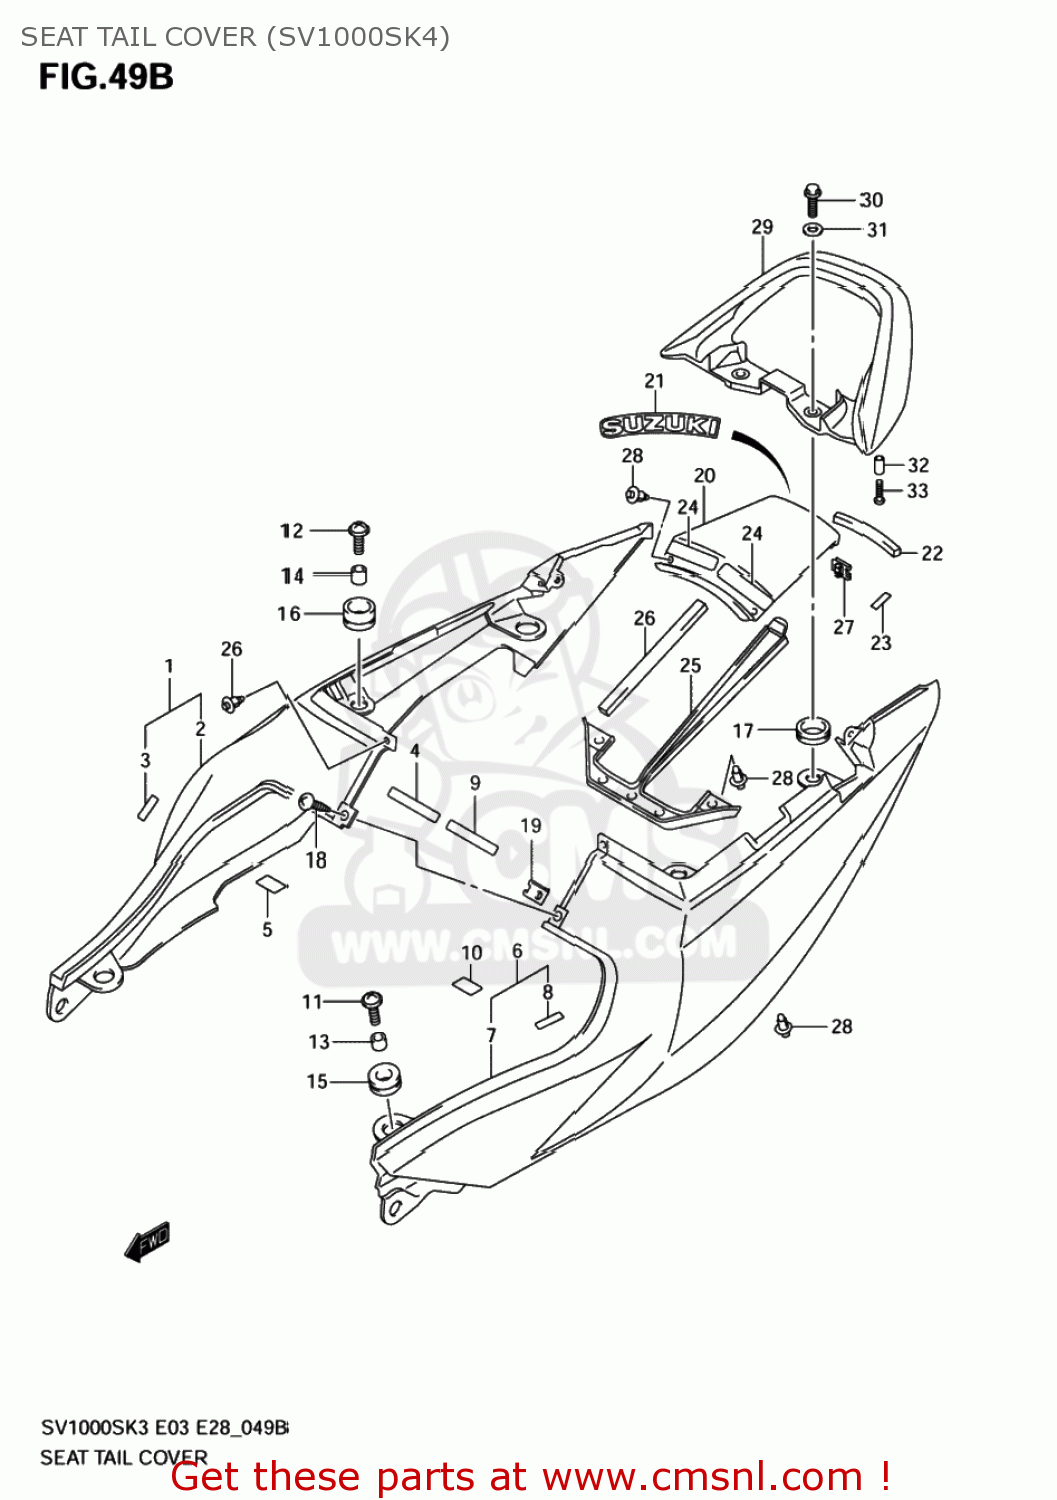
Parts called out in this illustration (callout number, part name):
1	COVER,SEAT TAIL
2	COVER,SEAT TAIL
3	TAPE,COVER
4	TAPE,SEAT TAIL COVER NO.2 FR
5	PROTECTOR,FRAME COVER
6	COVER,SEAT TAI
7	COVER,SEAT TAIL,L
8	TAPE,COVER
9	TAPE,SEAT TAIL COVER NO.2 FR
10	PROTECTOR,FRAME COVER
11	SCREW(6X25)
12	SCREW(6X25)
13	SPACER(6.5X10X9.4)
14	SPACER(6.5X10X9.4)
15	CUSHION
16	CUSHION,SEAT TAIL COVER CTR
17	CUSHION
18	SCREW
19	NUT
20	COVER,SEAT TAIL CTR
21	EMBLEM,SUZUKI
22	CUSHION,SEAT TAIL COVER CTR
23	TAPE,SEAT TAIL COVER
24	TAPE,COVER
25	COVER,SEAT TAIL RR
26	CUSHION,SEAT TAIL COVER
27	NUT
28	CLIP(BLACK)
29	HANDLE,PILLION RIDER
30	BOLT
31	WASHER(8.5X24X2.3)
32	SPACER(6.5X9X18)
33	SCREW(6X25)
